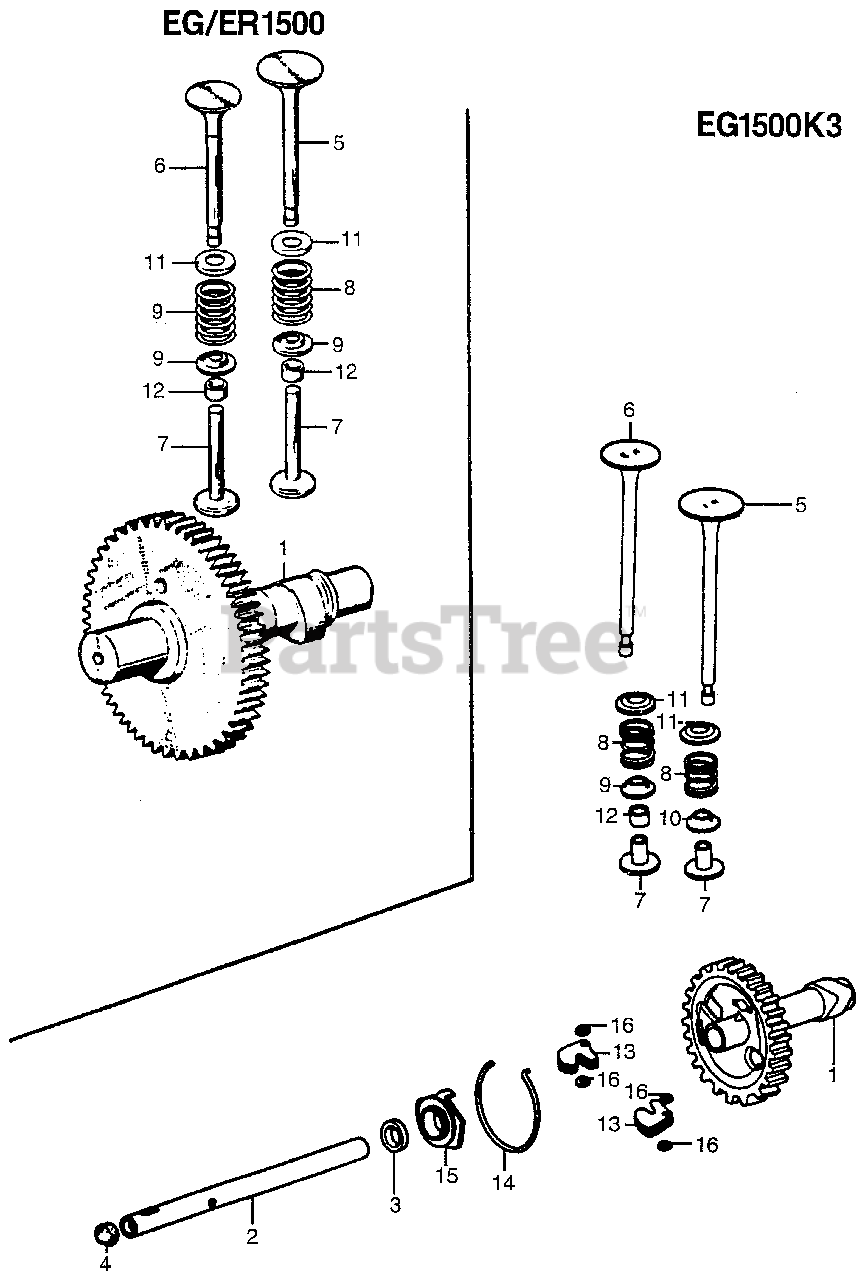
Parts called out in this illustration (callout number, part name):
5	VALVE, IN. (NOT AVAILABLE)
6	VALVE, EX. (NOT AVAILABLE)
7	LIFTER, VALVE
8	SPRING, VALVE (NOT AVAILABLE)
9	RETAINER, VALVE SPRING (NOT AVAILABLE)
11	SEAT, VALVE SPRING (NOT AVAILABLE)
12	ADJUSTER, TAPPET CLEARANCE
